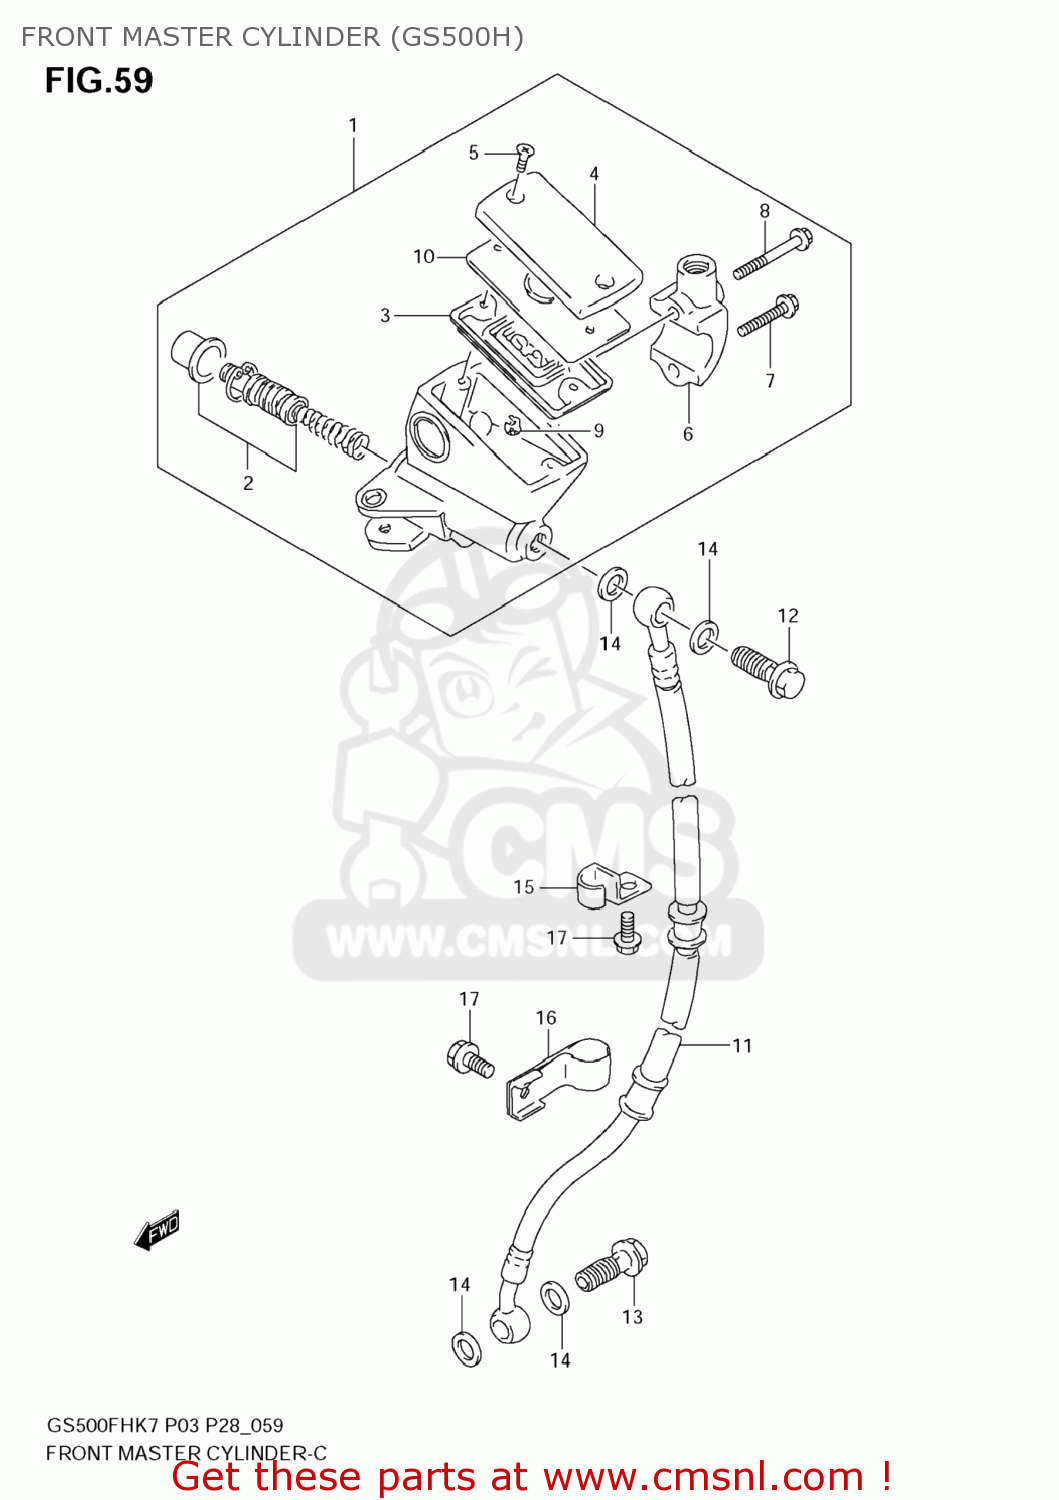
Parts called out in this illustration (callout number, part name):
1	CYLINDER ASSY
2	PISTON/CUP SET
3	DIAPHRAGM
4	CAP
5	SCREW
6	HOLDER
7	BOLT
8	BOLT UPPER
9	PROTECTOR
10	PLATE
11	HOSE, FRONT BR
12	BOLT UNION
13	BOLT UNION
14	WASHER(10X15X1.5)
15	CLAMP,FR BRAKE HOSE
16	CLAMP,FR BRAKE HOSE NO.2
17	BOLT
